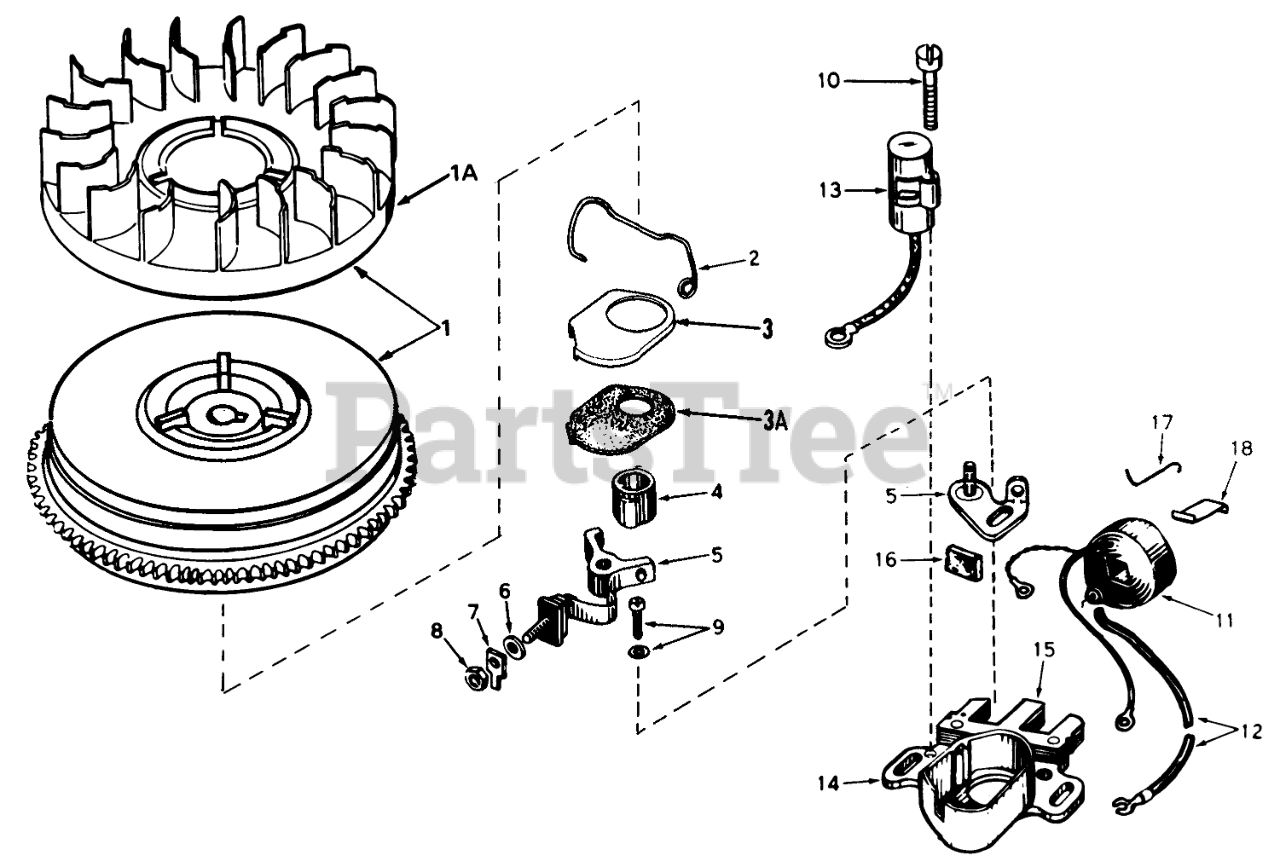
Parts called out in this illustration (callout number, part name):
1	Flywheel (Incl. #1A, 3 & 3A)
2	Spring Breaker Box
3	Cover-Dust
3A	Gasket, Dust Cover
4	Cam-Breaker
5	Breaker Assy.
7	Terminal, Ground
8	Nut Terminal
9	Breaker Screw
10	Condenser Screw
11	Coil Assy. (Incl. #12)
12	Wire, Lead
13	Condenser
14	Core & Plate
15	Stator Assy. (Incl. #2, 3, 3A, 5 thru 14 & 16 thru 18)
16	Felt,Cam Wiper
17	Clip, Coil
18	Spring Coil Wedge
